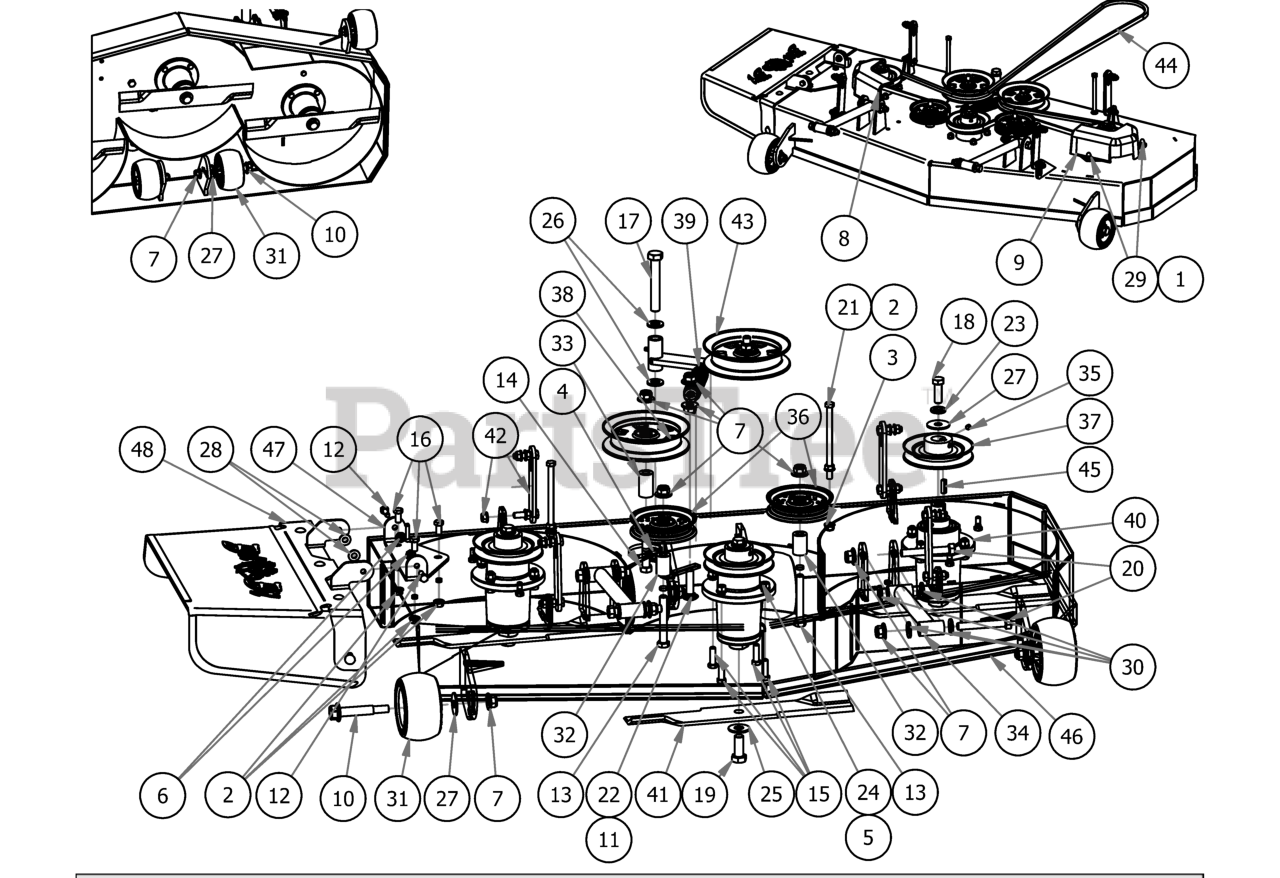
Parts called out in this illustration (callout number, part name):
1	Acorn nut-pulley Cover
2	3/8" Flange Nut
3	3/8" Nylock Flange Nut
4	5/8-11 Nylon Insert Jam Half Nut
5	3/8" Hex Nut
6	5/16" Nylon Flange Nut
7	1/2-13 Nylon Flange Nut
8	pulley cover chute side
9	pulley cover non-chute side
10	Deck Wheel Bolt
11	1/2 x 2" Carriage Bolt
12	5/16-18 x 1 GR 5 Hex Bolt Zinc
13	1/2 x 3 1/2 Flange Bolt Grade 8
14	1/2" x 4" Bolt (Grade 8)
15	3/8" x 1 1/4" Hex Bolt
16	3/8" x 3/4" Hex Bolt
17	5/8" x 4" Hex Bolt
18	1/2"-20 x 1 1/2 - Grade 5 Fine Thread Bolt
19	5/8 x 1 1/2 Grade 8 Hex Bolt (Fine)
20	1/2-13 x 3 1/2 GR 5 Hex Bolt
21	3/8-16 x 5 1/2 Hex Bolt
22	.517 Square Hole Round Washer
23	1/2" Lock Washer Zinc
24	3/8" Lock Washer
25	5/8'' Flat Washer
26	.630 ID Plastic Washer
27	1/2" Belleville Washer
28	.360 ID Plastic Washer
29	.360 ID Plastic Washer-Black
30	.505 Nylon Spacer
31	Deck Wheel
32	.502 ID X .750 OD X 1.500 Long Spacer
33	1 3/4" Pulley Spacer
34	MZ/ZT Deck Locator
35	5/16 Set Screw
36	4 3/4 Idler Pulley - ABFI-76
37	5" Spindle Deck Pulley
38	5-3/4 Idler Pulley
39	Deck Idler Spring
40	Spindle Assembly
41	16 1/4" Bad Boy Blade
42	Deck Hanger Assembly
43	2017 54"/48" Deck Idler Assembly
44	B147 Deck Belt
45	1/4" x 1" Key
46	2017 48" ZT Deck
47	Discharge Chute Hanger (deck mounted)
48	ZT Chute Assembly
